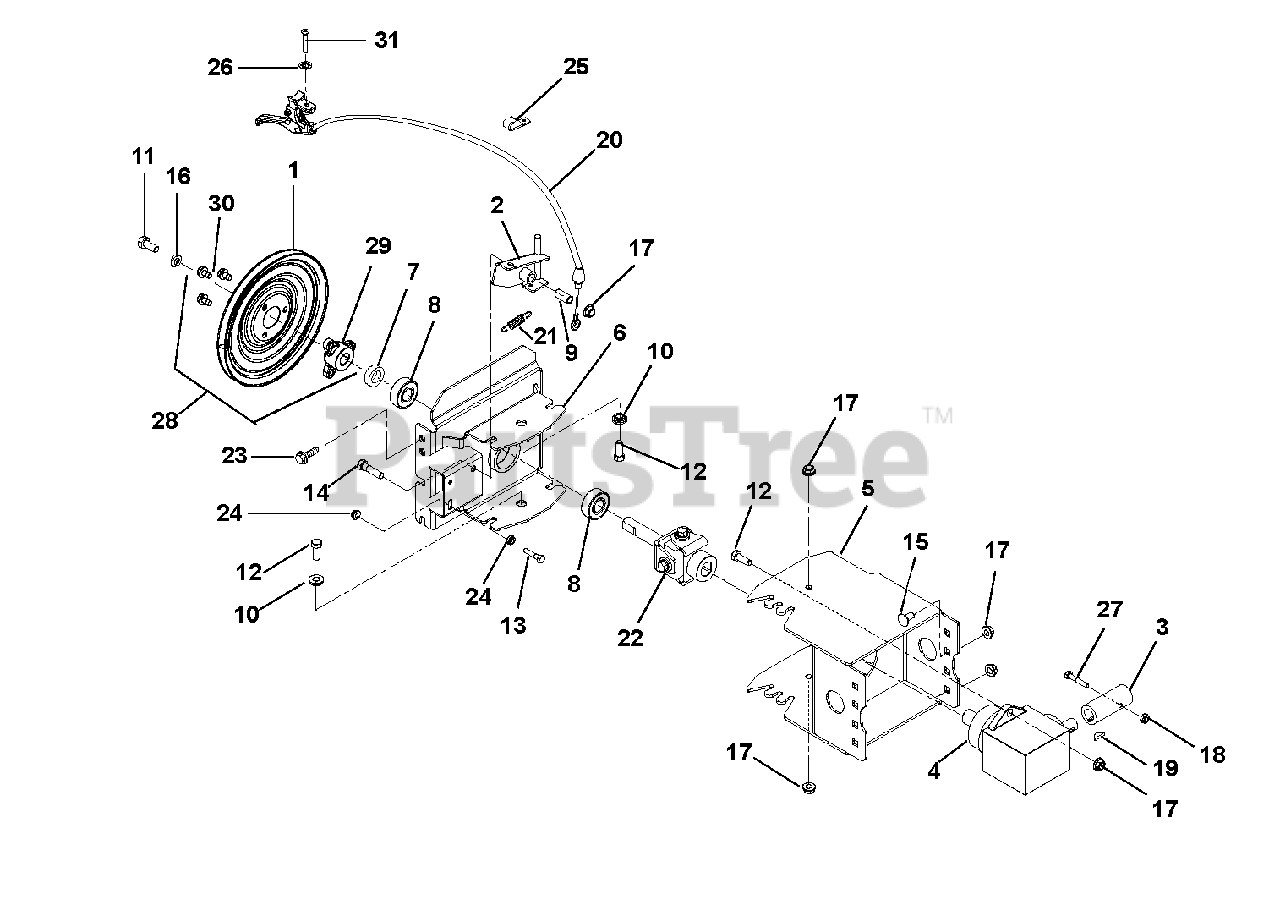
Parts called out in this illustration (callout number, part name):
1	Pulley, Attachment (Included in item 28)
2	Arm, Pivot Lock
3	Hub, Coupling
4	Gear Box Assembly
5	Adapter with Decal, Brush Frame
6	Adapter, Broom Frame
9	Bushing, Sleeve
10	Bushing, Flange
11	Bolt, Hex .31-24 x .75
12	Bolt, Hex .38-16 x 1.00
13	Bolt, Hex .25-20 x 1.50
14	Bolt, Hex .38-16 x 1.75
15	Bolt, Round Head Square Neck .38-16 x .75
16	Washer, Lock .312 x .097
17	Nut Locking Top Flange .38-16
18	Nut Locking Top Flange .25-20
19	Key, Woodruff .188 x .75 x .313 SAE 9
20	Cable, Remote Brush Lock
22	Universal Joint Assembly
23	Screw, Tapping Hex Washer Head Thread Rolling .31-18 x .75
24	Nut, Locking Serrated Flange .25-20
26	Washer, Lock, Internal .250
27	Bolt, Hex .25-20 x 1.75
28	Pulley Assembly (Includes Items 1, 29, 30)
29	Hub, Pulley (Included in item 28)
30	Screw, Tapping Hex Washer Head Thread Rolling .31-18 x .50 (Included in item 28)
31	Screw, Machine Oval Head .25-20 x 1.50
